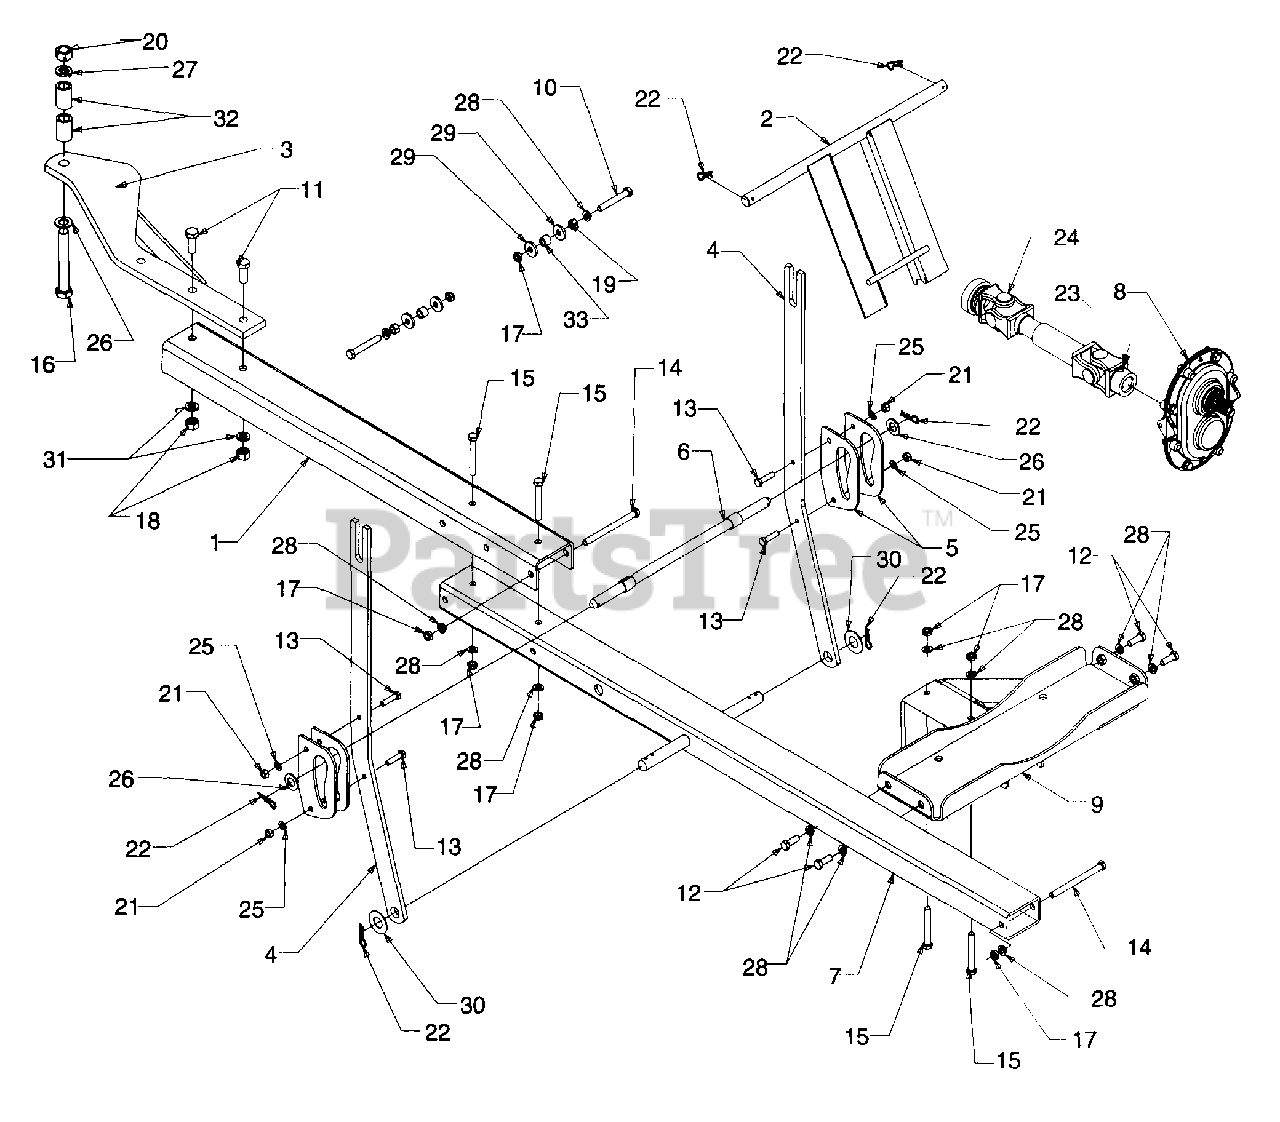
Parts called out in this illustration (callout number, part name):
9	BRKT ASM:HSG:MT
10	HHCS:3/8-24:2.50:GR5:SPEC
11	HHCS:1/2-13:1.25:GR2:STD
12	HHCS:3/8-16:1.00:GR5:STD
13	HHCS:5/16-18:1.25:GR5:STD
14	HHCS:3/8-24:4.50:GR5:STD
15	HHCS:3/8-24:2.75:GR5:STD
16	HHCS:5/8-18:4.50:GR5:STD
17	NUT:JAM:3/8-24:INS LOCK
18	NUT:1/2-13:GRA:HX
19	NUT:3/8-24:GRA:HX
20	NUT:5/8-18:GRD:HX
21	NUT:5/16-18:GRB:HX
22	PIN:COT:.125 X 1.75 INTERNAL
23	PIN:SPIROL:5/16:2.50
24	SHF:DR:UNIV X 1344 LG
25	WASH:LOCK:5/16:REGULAR DUTY
26	WASH:FL:.635 X 1.125 X .090
27	WASH:LOCK:5/8:REGULAR DUTY
28	WASH:LOCK:3/8:REGULAR DUTY
29	WASH:FLAT:.385 X 1.0 X .135
30	WASH:FL:.78ID X 1.590 OD X .06
31	WASH:LOCK:1/2:REGULAR DUTY
32	HUB .635 ID X 1.00 OD X 1.50
33	SPCR:.375 IDX .625 OD X .445 LG
